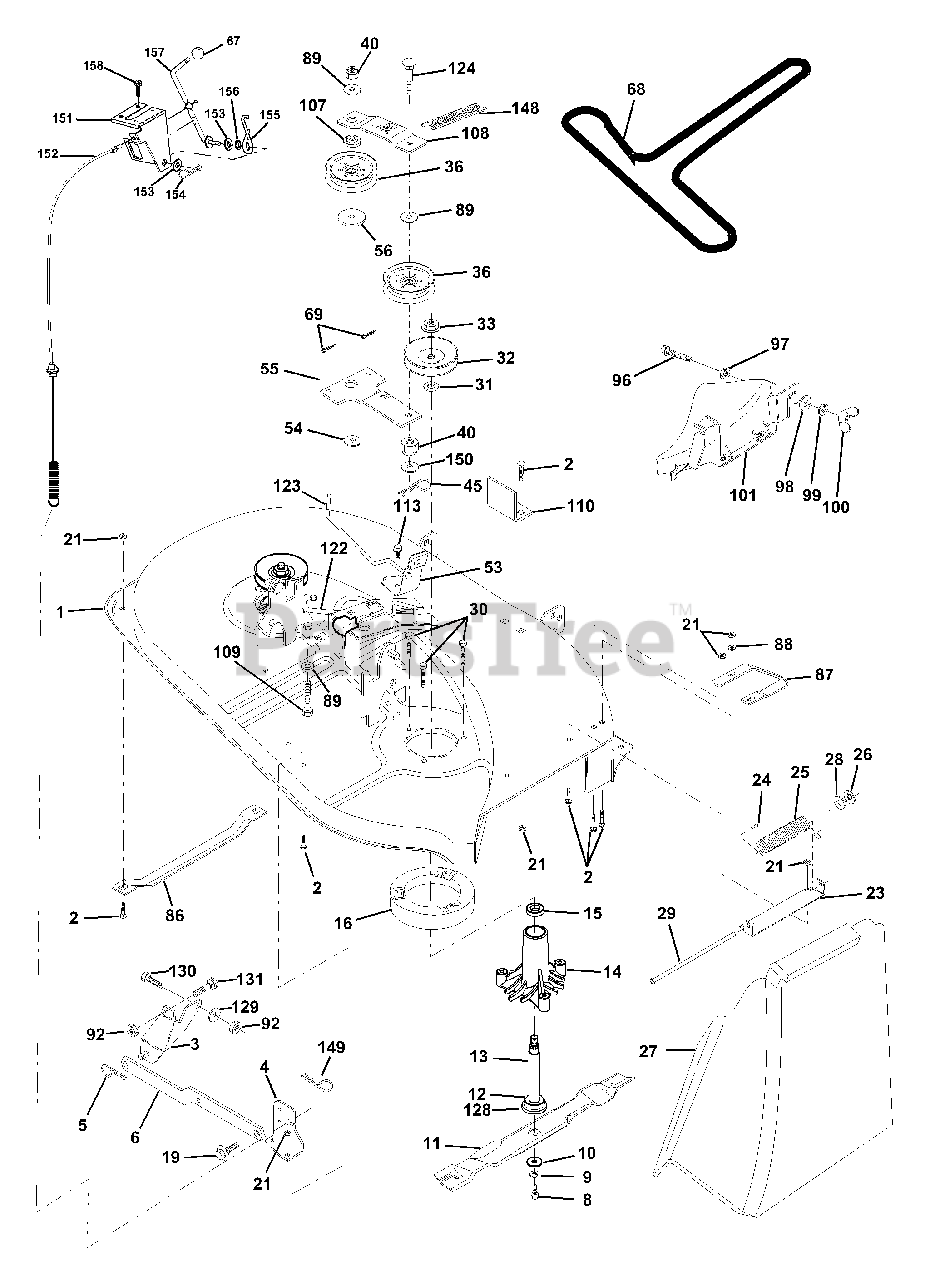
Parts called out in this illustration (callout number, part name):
1	Deck Asm Weldment
2	Bolt Rdhd Sqnk 5/16-18unc X 3/4
3	Bracket Asm Fr Sway Bar 38/42
4	Bracket Asm Deck Sway Bar
5	Retainer Spring
6	Arm Suspension Rear
8	Bolt 3/8 - 24 X 1.25 Gr 8
9	Washer Lock Hvy 3/8
10	Washer Hard Blade Mower Vented
11	Blade Mower Mulching 38"
12	Bearing Ball #6024 (Mandrel)
13	Shaft Asm W/lower Bearing
14	Housing Mandrel Vented
15	Bearing Ball Mandrel
16	Stripper Mower Vented
19	Bolt Shoulder
21	Nut Crownlock 5/16-18 UNC
23	Bracket Deflector Mower
24	Cap Sleeve 80x 112 Blk Mower
25	Spring Torsion Deflector 2 52
26	Nut Push Phos & Oil
27	Shield Deflector
28	Washer 11/32 X 5/8 X 16 Ga
30	Screw Thdrol Rolling Washer Head
31	Washer Spacer Mower Vented
32	Pulley Mandrel
33	Nut 9/16 Toplock Flng Oil Dip
36	Pulley Idler Flat 3 060
40	Nut Crownlock 3/8-16 UNC
45	Spring Retainer 1" Zinc/cad
54	Washer Hardened
56	Spacer Retainer Mower
67	Knob Rd 3/8-16 Plstc Thds Blk
68	V-Belt Mower
69	Pin, Cotter 3/32 x 3/4
86	Runner,LH
88	Washer 11/32 x 3/4 x 16 Ga.
89	Washer 13/32 x 1 x 12 Ga.
92	Nut Lock Hex W/Ins 3/8-16 Unc
96	Bolt 3/8-16 x 1-1/4 Mulcher
97	Nut Crownlock 3/8-16 UNC
98	Washer 13/32 x 1-1/4 x 16 Ga.
99	Washer Lock Hvy Hlcl Spr 3/8
101	Cover Asm Mulching 38"
107	Spacer, Retainer
108	Stiffener, Idler Arm
109	Bolt, Hex Head 3/8-16 x 2-1/2
110	Upstop Deck Front 38"
113	Screw 5/16-18 X 3/4
122	Rod, Brake, LH
123	Rod, Brake, RH
124	Bolt, Carriage 3/8-16 x 1-3/4
128	Washer Felt
129	Washer 13/32 x 13/16 x 12 Ga.
130	Bolt, Fin Hex 3/8-16 UNC x 1 Gr. 5
131	Bolt, Rdhd Sqnk 3/8-16 x 1
148	Spring, Idler Return
149	Retainer Spring Yellow Zinc
150	Washer 9/32 x 3/4 x 16 Ga.
151	Bracket Clutch Cable
152	Clutch Cable 38"/46"
153	Washer Flat 3/8" Type B
154	Spring Retainer
155	Spring Retention Lvr Clutch Cab
156	Spacer Clutch Cable
157	Rod Clutch Cable 3/8"
158	Screw Hex Thdcut 1/4-20 x 5/8
